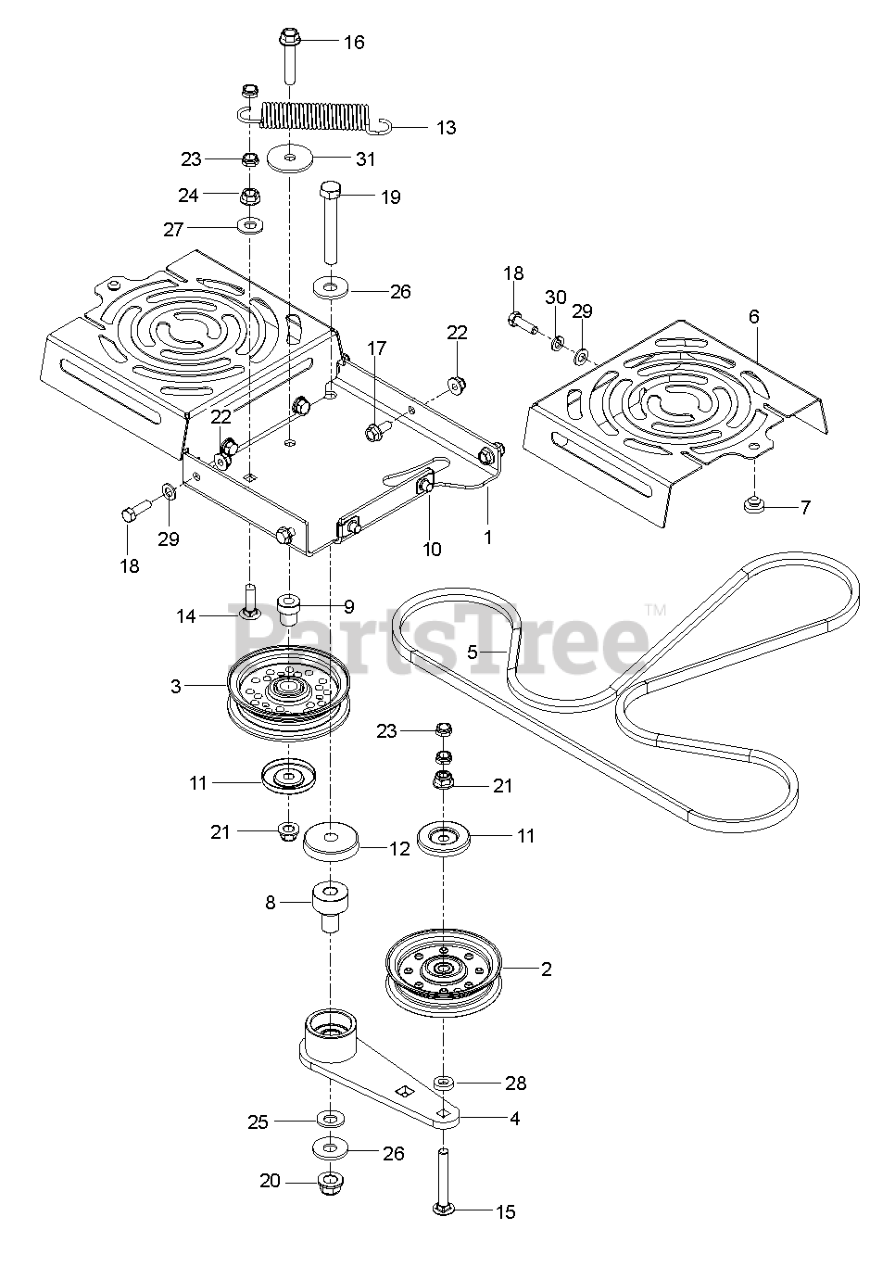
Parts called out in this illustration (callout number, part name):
1	PLATE.PNT.IDLER.SUPPORT.E-DIP
2	IDLER PULLEY
3	PULLEY.IDLER.FLAT.46.PR.DR.
4	ARM, IDLER, STEEL, W/BGS
5	BELT, HYDRO, 3400
6	SHIELD FAN BLACK
7	GROMMET, BUMPER
8	PIVOT, BEARING
9	PIVOT, IDLER
10	U-CLIP 5/16-18 NUT RETAINER
11	DUST SHIELD
12	SHIELD, DUST
13	SPRING, PUMP
14	BOLT.3/8-14X1.25
15	RHSNB 3/8-16 X 2.75
16	HHFS 3/8-16 X 2.0 GD 5
17	HHFS 5/16-18 X 3/4
18	HCS 5/16C X 1
19	HCS 1/2-13 X 3-1/4 GD 5 ZD
20	NUT, 1/2-13 HEX FLG NYLOC ZD
21	NUT 3/8-16 HEX FLG NYLOC ZD
22	5/16-18 NYLOC FLANGE NUT
23	NUT HEX 3/8-16 NYLON, THIN
24	NUT 3/8C WHIZ
25	CONTACT BELLSPR 1/2
26	WASHER.9/16 X 1 3/8 X 12 GA.
27	WASHER 3/8 FLAT
28	WASHER 3/8 X 3/4 X .187 TK
29	WASHER
30	WASHER 5/16 LOCK
31	WASHER, 3/8 SPEC
